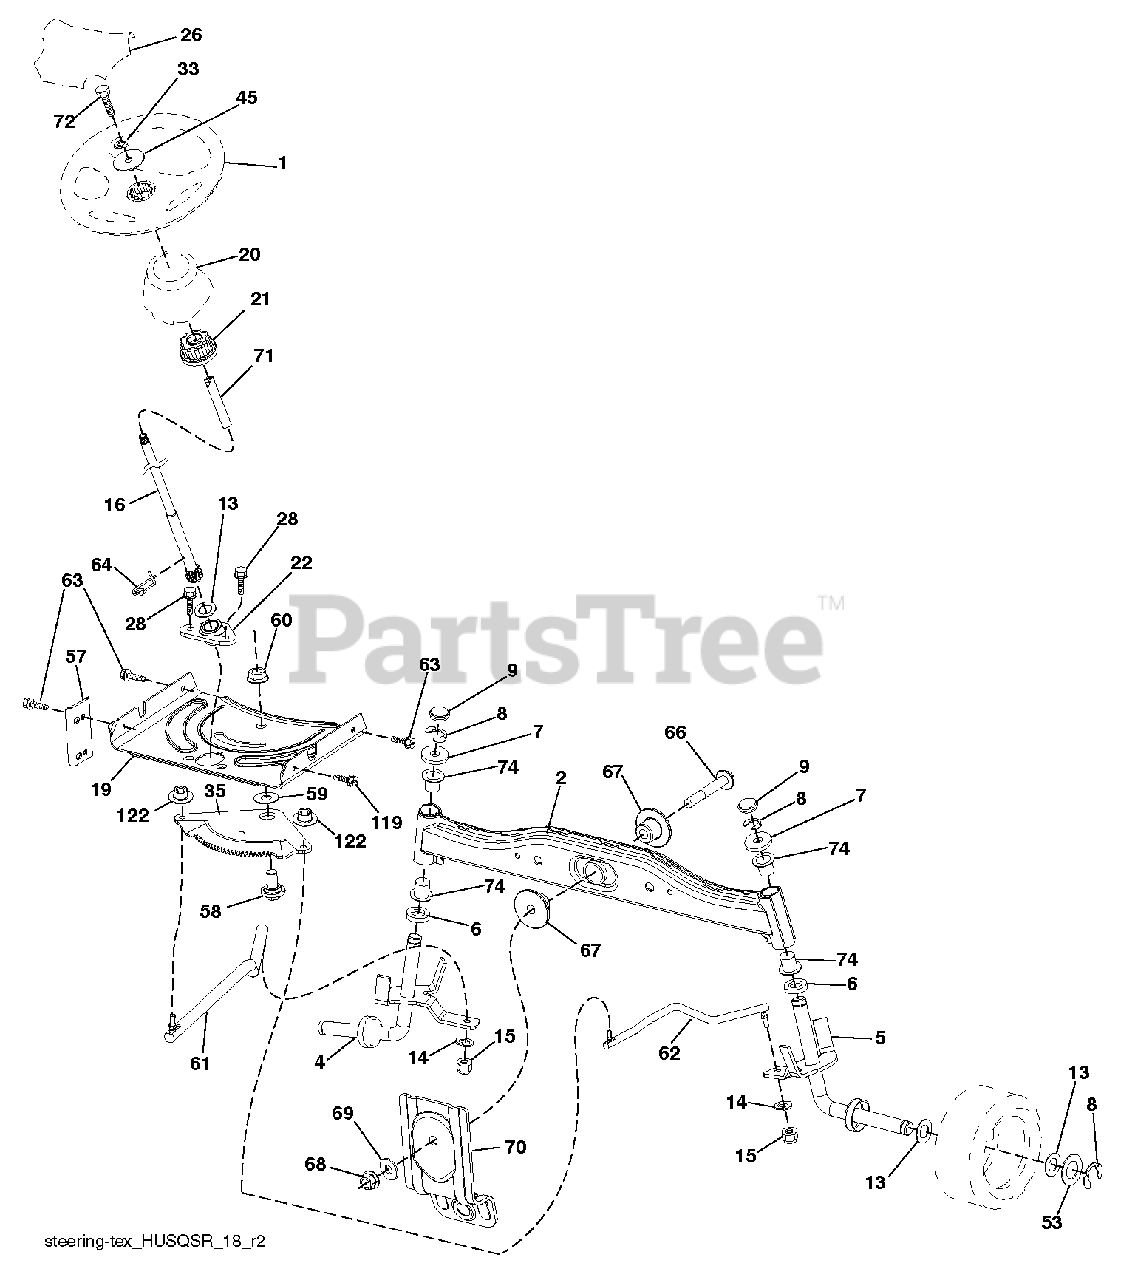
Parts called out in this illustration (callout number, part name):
1	WHEEL.STEER.HUSQ.SR.498.OVMLD
2	AXLE HALF ASM-WELDED
4	SPINDLE.STEERING.ASM.LH.13".TI
5	SPINDLE.STEERING.ASM.RH.13".TI
6	THRUST WASHER
9	CAP.SPINDLE.BLACK
14	WASHER, LOCK 3/8
15	NUT CROWNLOCK 3/8-24
16	SHAFT.STEER.3/4.PLATED.TEX
19	PLATE.STEER.DDL.NLT/NG
20	STEERING.BOOT.HUSQ.LT
21	ADAPTER, WHEEL STNG..
22	STEERING.SUPT.LOWER.
26	INSERT.CAP.WHL.STRG.HUSQ.PREM
28	SCREW, 3/8-16X3/4
33	LOCKWASHER
35	GEAR.SECTOR.PLATE.DDL.
45	WASHER.11/32
53	WASHER.HARDENED
57	BRACKET.UPSTOP.TEX
58	BOLT.SHOULDER.SECTOR.P
59	WASHER.THURST.SECTOR.S
60	NUT FLANGE LOCK 5/8-11
61	DRAGLINK.LH.BALLSTUD.D
62	DRAGLINK.RH.BALLSTUD.D
63	SCREW
64	RETAINER.CLIP.SPRING.S
66	BOLT HEX FGHD 7/16-14 X 3 SERR
67	BUSHING.PM.FRONT AXLE
68	NUT.LOCK.FLANGE.7/16
69	WASHER.1.5X.505X.118
70	BRACKET.SUSP.MWR.FRT.30"SRD
71	SHAFT.EXTEN.STRG.SPLINE
72	BOLT 5/16-18 X 4 W/PATCH
74	BRNG T
119	SHOULDER BOLT 5/16-18TT
122	CAP.GEAR.SECTOR.TEX
